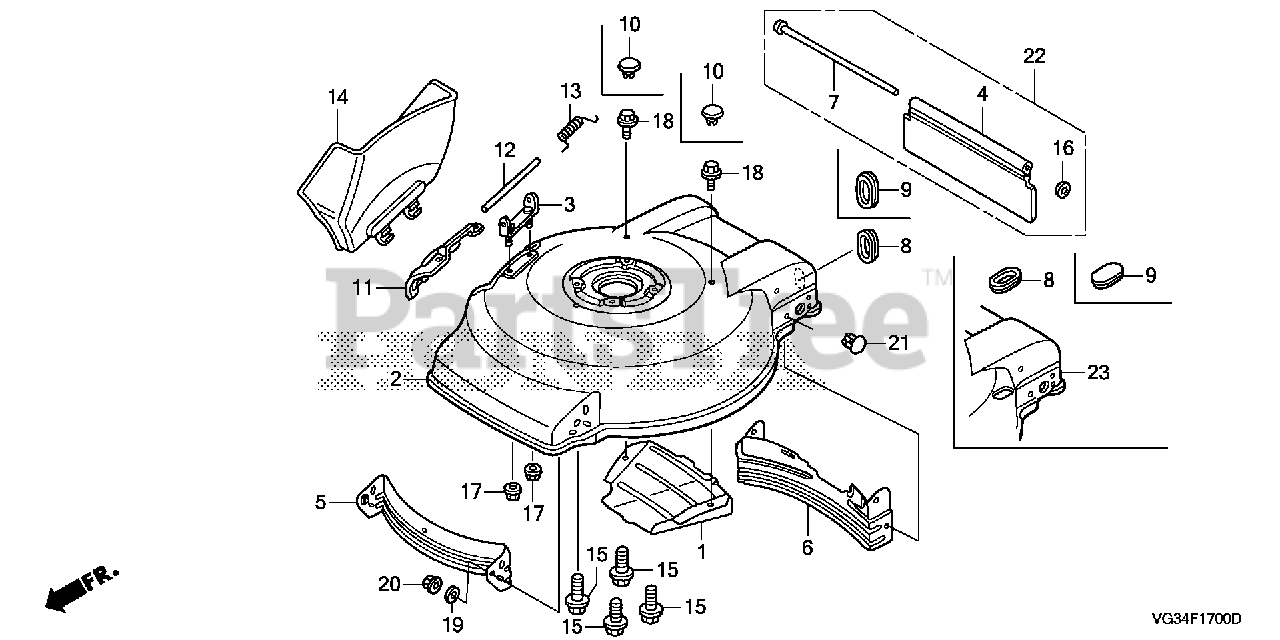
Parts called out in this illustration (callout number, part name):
1	COVER, BELT
3	HINGE, DISCHARGE GUARD
5	SCROLL, FR.
6	SCROLL, RR.
7	SHAFT, RR. SHIELD (405MM)
8	GROMMET, CABLE (HOLE)
11	GUARD, DISCHARGE *NH105* (MAT BLACK)
12	SHAFT, DISCHARGE GUARD
13	SPRING, GUARD RETURN
14	CHUTE, SIDE DISCHARGE *NH105* (MAT BLACK)
15	BOLT, FLANGE (5/16-24X1")
16	NUT, PUSH (3.96MM) (FLAT ROUND TYPE)
17	NUT, FLANGE (6MM)
18	BOLT, FLANGE (6X10)
19	WASHER, PLAIN (5/16)
20	NUT, FLANGE (8MM)
22	KIT, RR. SHIELD
23	HOUSING, CUTTER *NHB67M* (EMBOSS BRIGHT GRAY METALLIC)
